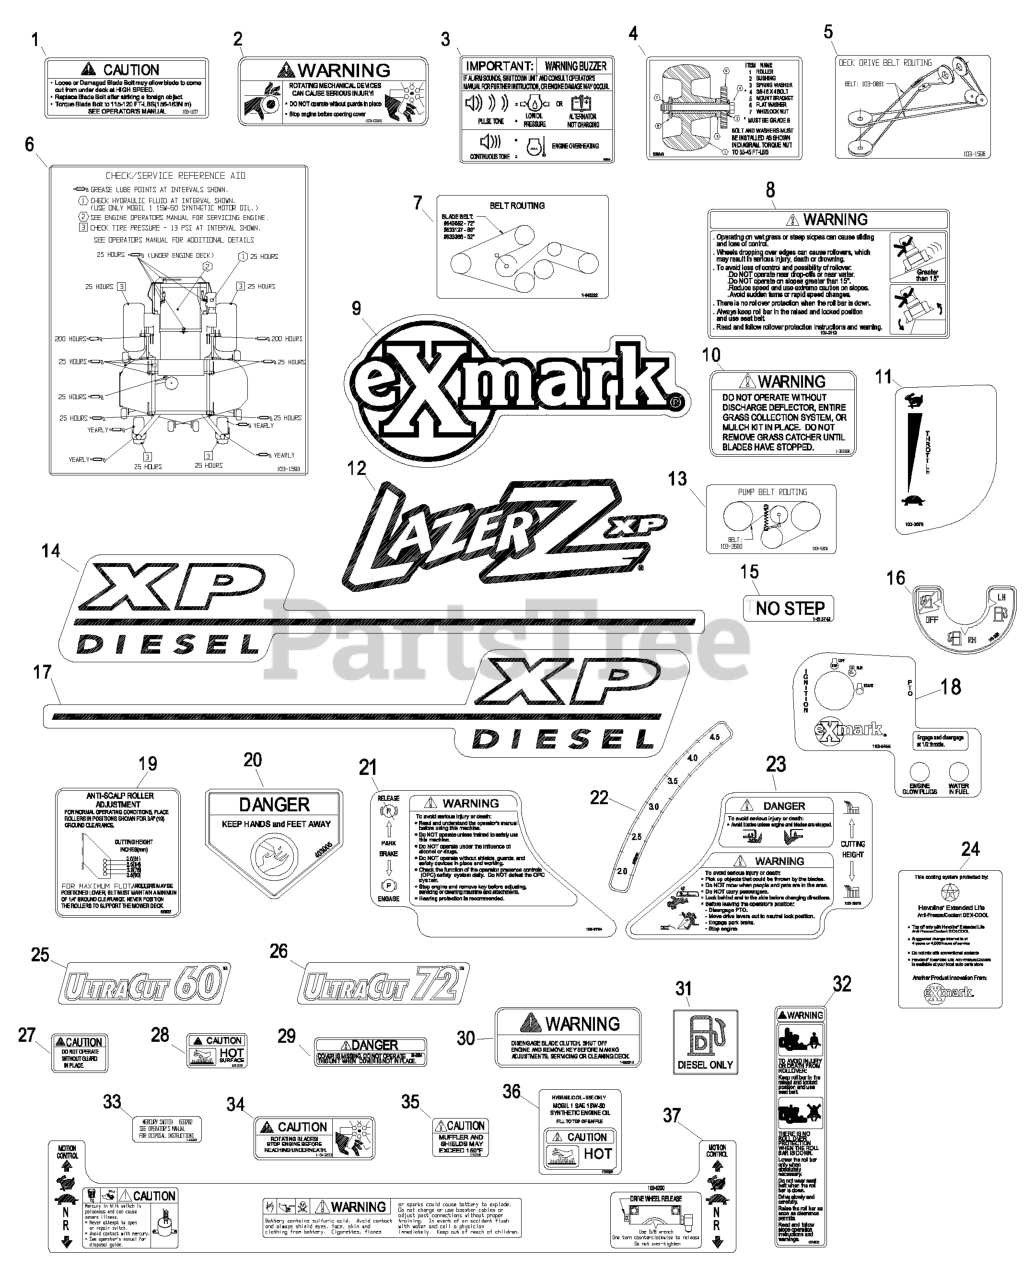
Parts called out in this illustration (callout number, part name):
1	DECAL,BOLT TORQUE
3	DECAL-BUZZER, WARNING
4	DECAL,ROLLER MOUNTING
5	DECAL,BELT ROUTING XP
6	DECAL,CHECK/SERVICE XP *
7	DECAL,BELT ROUTING
8	DECAL-WARNING
9	DECAL,EXMARK LOGO
10	DECAL-WARNING, DISCHARGE
15	DECAL,NO STEP
16	DECAL-VALVE, FUEL
17	DECAL,XP HOOD RH
18	DECAL,IGNITION/PTO XP
19	DECAL,ANTISCALP
20	DECAL-DANGER
21	DECAL,PARK BRAKE
22	DECAL-HEIGHT, DECK
23	DECAL,CUTTING HEIGHT
24	DECAL,SHELL COOLANT
25	DECAL,ULTRACUT 60
26	DECAL,ULTRACUT 72
27	DECAL-GUARD
28	DECAL-CAUTION
29	DECAL-COVER, MISSING
30	DECAL,WARNING
31	DECAL-FUEL
32	DECAL-WARNING, FOLDING RO
33	DECAL-SWITCH, MERCURY
34	DECAL-FAN, RADIATOR
37	DECAL,CONSOLE TOP
